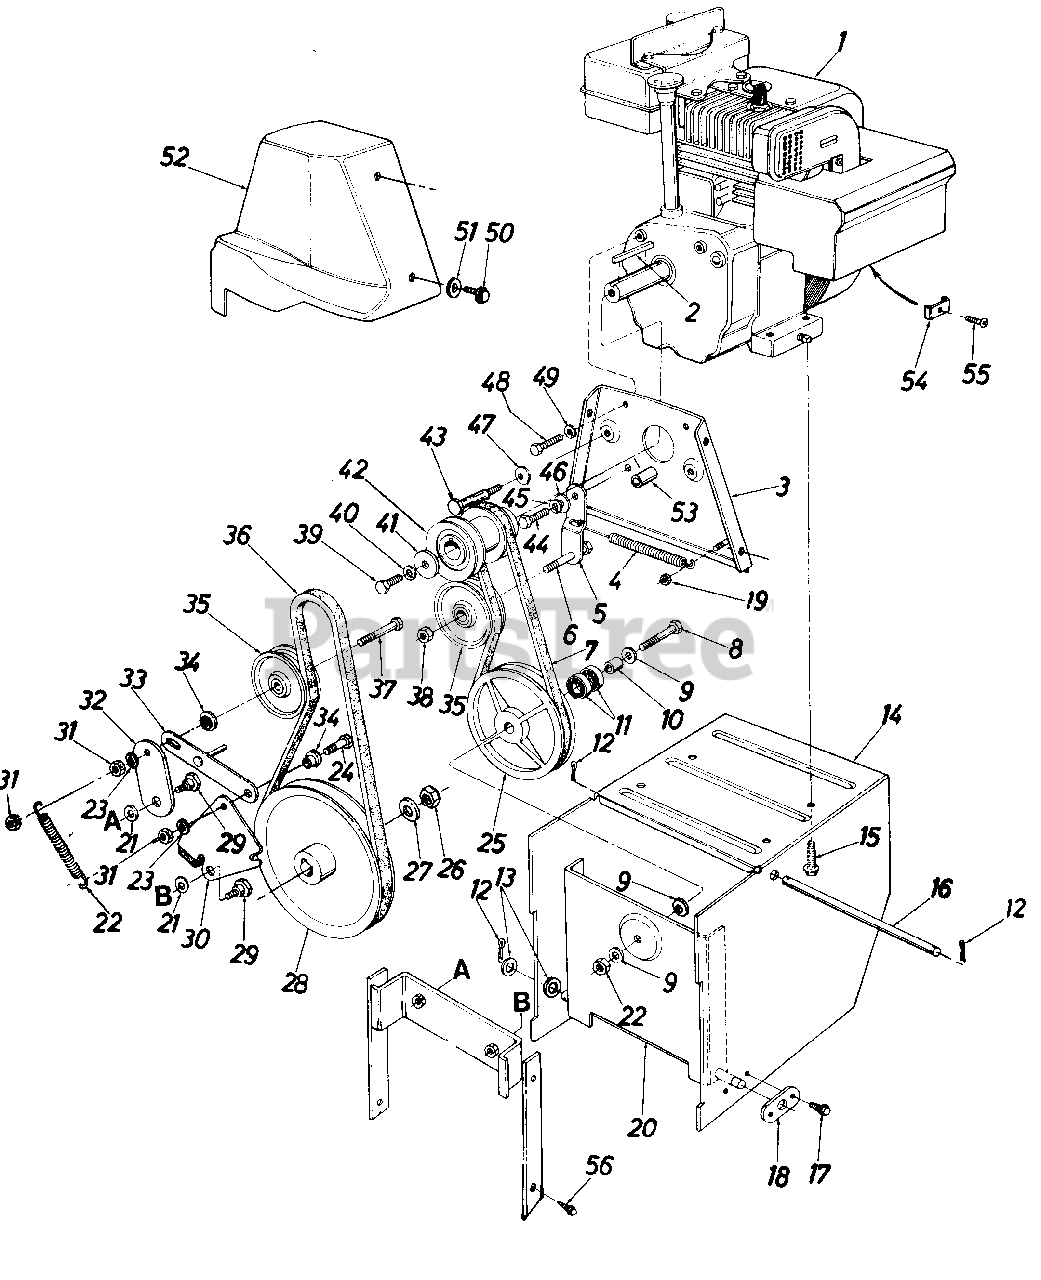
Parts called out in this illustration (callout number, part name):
1	Engine
2	Sq. Key 3/16" x 1.50" Lg.
3	Engine Plate Ass'y.
4	Extension Spring .50" O.D. x 3.97" Lg.
5	Drive Clutch Idler Brkt.
6	Hex Bolt 3/8-24 x 1.25" Lg.
7	V"-Belt 3/8" x 29.0" Lg.
8	Hex Bolt 3/8-24 x 1.50" Lg.
9	Bell-Wash. .40" I.D. x .88" O.D. x .06
10	Spacer.38" I.D. x .62" O.D. x.75" Lg.
11	Ball Brg. .62" I.D. x 1.38" O.D. x .44
12	Cotter Pin 3/32" Dia. x .75" Lg.*
13	Fl-Wash. .53" I.D. x 1.00" O.D. x .125
14	Frame Ass'y.
15	Hex Wash. Hd. Self-Tap Scr. 3/8-16 x 1.25" Lg.
16	Shaft .50" Dia. x 9.50" Lg.
17	Hex Wash. Hd. Self-Tap Scr. 1/4-20 x .50' Lg.
18	Axle Bracket
19	Hex L-Nut 1/4-20 Thd.
20	Drive Pulley Support Brkt. Ass'y.
21	Bell-Wash. .40" I.D. x 1.13" O.D.
22	Extension Spring .50" O.D. x 3.97" Lg.
23	L-Wash. 3/8" I.D.
24	Hex Scr. 3/8-16 x 1.25" Lg.
25	6.00" O.D. Drive Pulley Ass'y
26	Hex Jam Cent. L-Nut 5/8-18 Thd.
27	Fl-Wash. .64" I.D. x .94" O.D. x .06
28	1/2" V-Pulley .625" I.D. x 7.50" O.D.
29	Shld. Bolt .625" Dia. x .170" Lg. (3/8-16)
30	Brake Bracket Ass'y.
31	Hex Ins. L-Nut 3/8-16 Thd.
32	Auger Clutch Idler Brkt.
33	Brake Linkage Ass'y.
34	Shld. Spacer .625" I.D.
35	Flat Idler 2.25" O.D.
36	V-Belt 3/8" x 38" Lg.
37	Hex Bolt 3/8-16 x 2.25" Lg.
38	Hex Ins. Jam L-Nut 3/8-24 Thd.
39	Hex Bolt 3/8-24 x 1.50" Lg.
40	L-Wash. 3/8" I.D.
41	Fl-Wash. .40" I.D. x 1.25" O.D.
42	Double Groove Engine Pulley
43	Shld. Scr. .498" x 3.0" Lg.
44	Hex Bolt 5/16-24 x 1.00" Lg.
45	L-Wash. 5/16" I.D.
46	Shld. Spacer .320" I.D.
47	Bell-Wash. .40" I.D. x .88" x .06
48	Hex Bolt 5/16-24 x .62" Lg.
49	L-Wash. 5/16" I.D.
50	Hex Wash. Hd. Self-Tap Scr. 1/4-20 x .50" Lg
51	Fl-Wash. .28" I.D. x .75" O.D. x .06
52	Belt Cover
53	Spacer
54	Throttle Control Wire Clamp
55	Hex Sems Scr. #10-32 x .62" Lg.
56	Hex Wash. Hd. Self-Tap Scr. 3/8-16 x .75" Lg.
